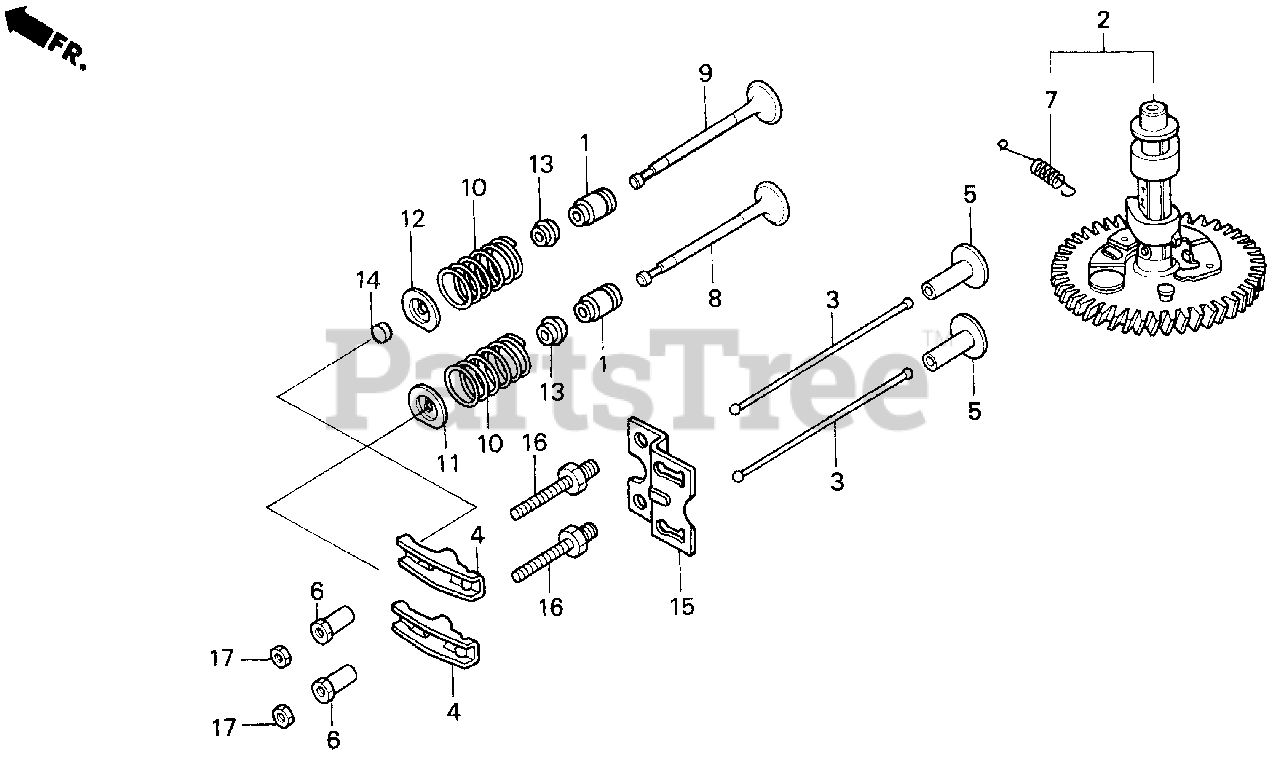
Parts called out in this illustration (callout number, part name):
1	SEAL, VALVE STEM
2	CAMSHAFT ASSY.
2	CAMSHAFT
3	ROD, PUSH
4	ARM, VALVE ROCKER
5	LIFTER, VALVE
6	PIVOT, ROCKER ARM
7	SPRING, WEIGHT RETURN
8	VALVE, IN.
9	VALVE, EX.
10	SPRING, VALVE
11	RETAINER, IN. VALVE SPRING
12	RETAINER, EX. VALVE SPRING
13	SEAT, VALVE SPRING
14	ROTATOR, VALVE
15	GUIDE, PUSH ROD
16	BOLT, PIVOT (8MM)
17	NUT, PIVOT ADJ.
